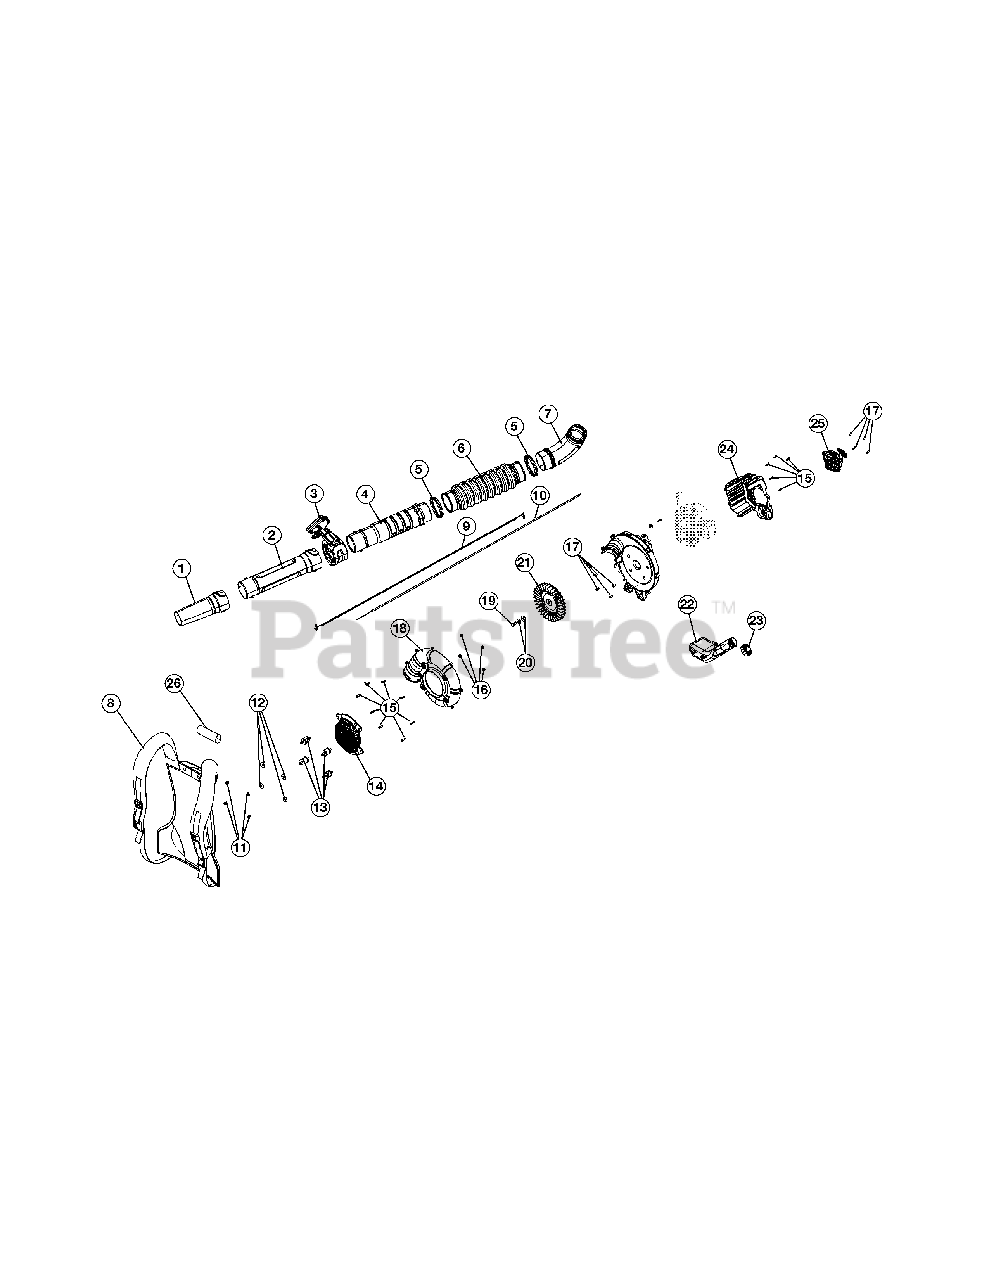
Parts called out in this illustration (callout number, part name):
2	Lower Blower Tube
3	Throttle Grip Assembly
4	Upper Blower Tube
10	Throttle Cable
11	Nut
12	Washer
13	Insulator Mount
14	Intake Cover
17	Screw
18	Impeller Housing Assembly
20	Impeller Hardware
21	Impeller
22	Fuel Tank Assembly
24	Housing Assembly
25	Starter Assembly
